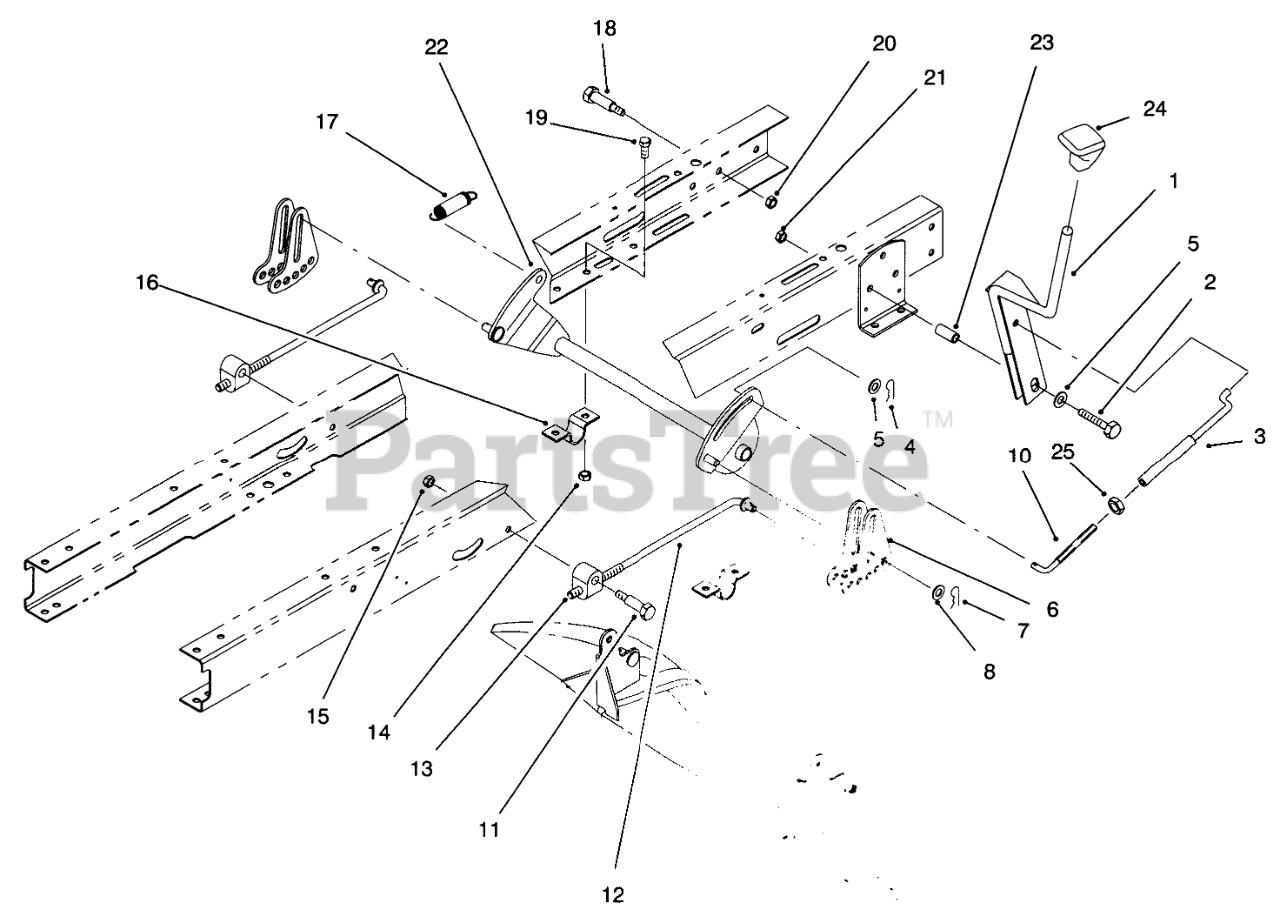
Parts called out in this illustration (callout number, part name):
1	Lever-H.O.C.
2	SCREW-HH
4	PIN-COTTER
5	WASHER-FLAT
6	Link-Adjusting H.O.C
7	PIN-COTTER
8	WASHER-HARDENED
10	LINK-HOC
11	SCREW-SHOULDER, HH
12	ROD-HANGER, REAR
13	TRUNNION-HOC
14	NUT-LOCK, NI
15	NUT-LOCK, NI
16	CLAMP-PIVOT, HOC
17	SPRING-EXTENSION
18	SCREW-SHOULDER, HH
19	SCREW-HH
20	NUT-LOCK, NI
21	NUT-LOCK, NI
22	Pivot-H.O.C.
23	SPACER
24	KNOB-SHIFT
25	NUT-JAM
